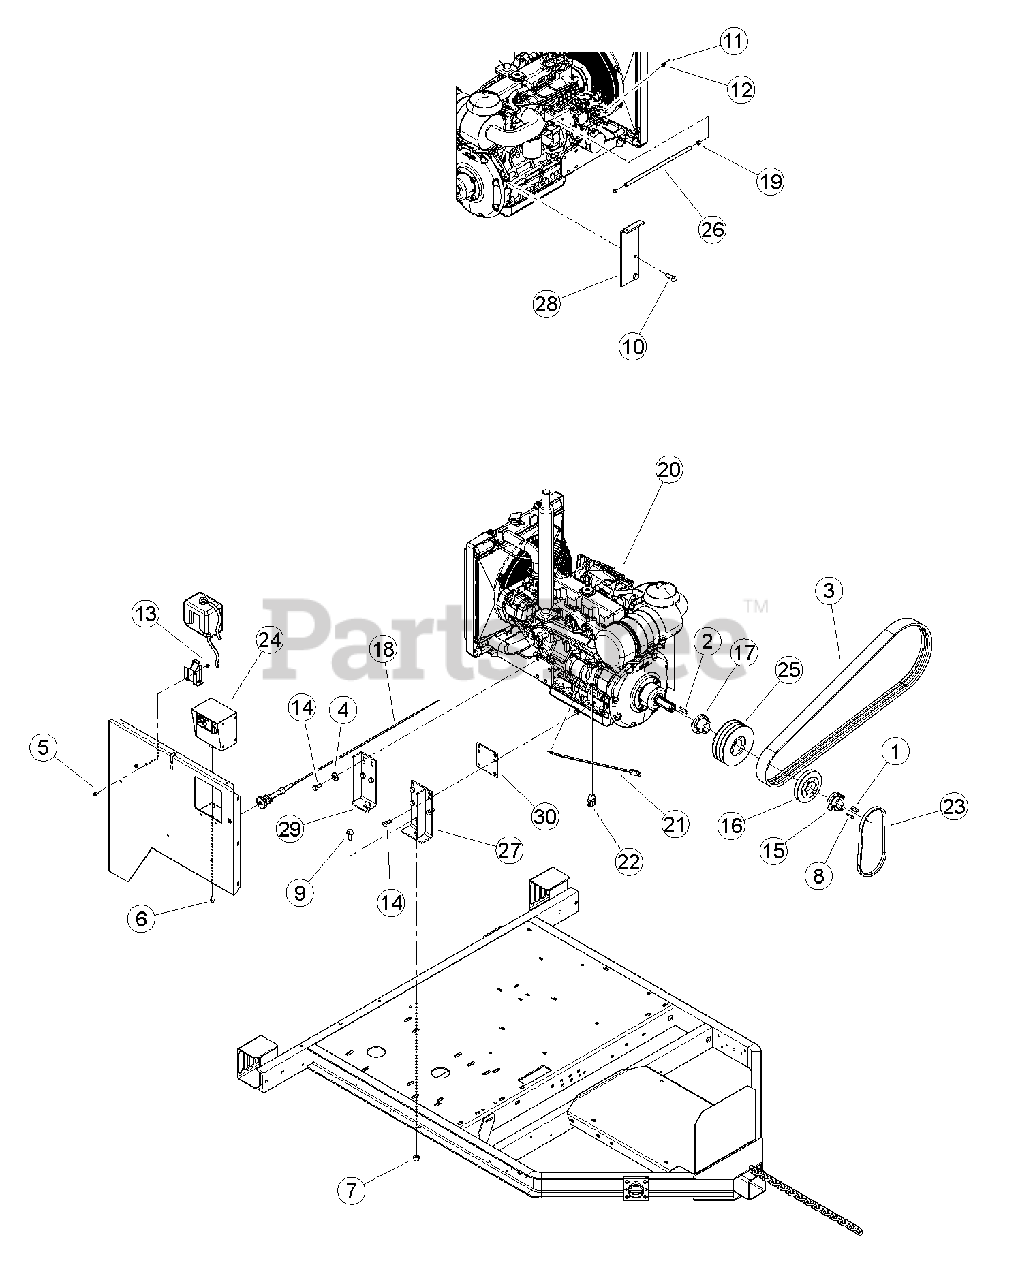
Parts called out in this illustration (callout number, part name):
1	KEY, 3/8 SQ X 1-1/4
2	KEY, 3/8 SQ 1-3/4
3	BELT, 3B90 BANDED
4	WASHER, 1/2" FLAT ZP
5	BOLT, 1/4-20 X 3/4 HWH GR5 CZP
6	BOLT, 5/16 X 3/4 FLANGE NC
7	NUT, 1/2-13 NYLOCK FLANGE
8	BOLT, 1/4-20 X 1-1/4 GR5 HHCS MAGNI 565 SILVER
9	BOLT, 1/2 -13 X 1-1/4 FLANGE NC
10	BOLT, M14-1.5 X 20 HEX HD GR 8.8
11	SCREW, #8-32 X 3/16 KNR CUP PT
12	PIN, 1/4" BOWDEN
13	NUT, 1/4-20 NYLOCK-FLANGE
14	BOLT, M12 X 1.25 X 25 GR 10.9 HEX HEAD ZP
15	BUSHING, SDS 1-7/16"
16	SHEAVE, 1B5.2 SDS
17	BUSHING, SD 1-7/16"
18	CABLE, DIESEL THROTTLE
19	CLAMP, 9/16 SPRING
20	ASSEMBLY, 50 HP KUBOTA ENGINE
21	CABLE, 72" POSITIVE BATTERY
22	CABLE, 72" NEGATIVE BATTERY
23	BELT, BX30
24	CONTROLLER, DSE - KUBOTA
25	SHEAVE, 3B6.8 SD
26	HOSE, 15 INCH FUEL LINE
27	WELDMENT, ENGINE MOUNT
28	ANGLE, SPRING ANCHOR
29	WELDMENT, FRONT ENGINE MOUNT
30	PLATE, MOUNT SPACER
